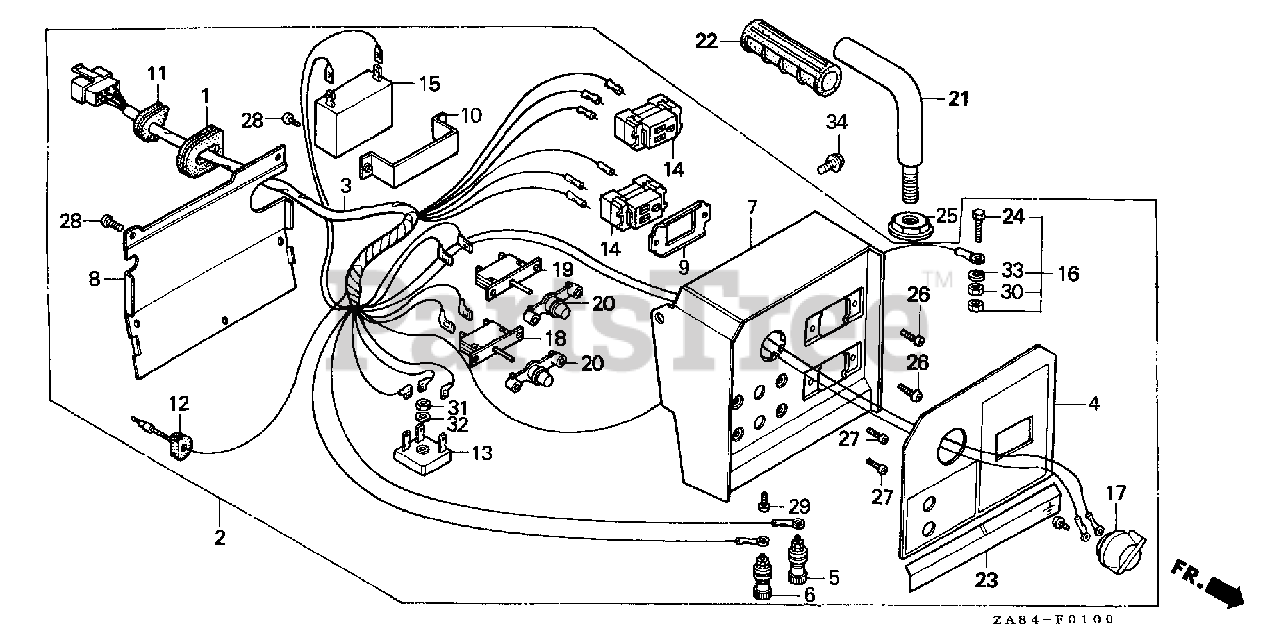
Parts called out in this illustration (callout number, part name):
1	GROMMET, WIRE
2	BOX ASSY., CONTROL *R8* (BRIGHT RED)
3	WIRE HARNESS ASSY.
4	MARK, SWITCH PANEL
5	TERMINAL, D.C. OUT (+)
6	TERMINAL, D.C. OUT (-)
7	BOX, CONTROL *R8* (BRIGHT RED)
8	COVER, CONTROL BOX
9	HOLDER, RECEPTACLE
10	HOLDER, CONDENSER
12	GROMMET, SWITCH WIRE
13	DIODE, D.C.
14	RECEPTACLE (15A/125V)
16	TERMINAL SET, GROUND
17	SWITCH ASSY., ENGINE STOP
17	SWITCH ASSY., ENGINE
18	PROTECTOR, CIRCUIT (DC)
19	PROTECTOR, CIRCUIT (A.C.)
20	LENS ASSY., PROTECTOR
21	HANDLE, CARRYING
22	GRIP, HANDLE
23	MARK, CONTROL BOX
24	BOLT, HEX. (6X22)
25	NUT, FLANGE (14MM)
26	SCREW, PAN (3X8)
27	SCREW, PAN (3X12)
28	SCREW, PAN (4X8)
29	SCREW, PAN (4X16)
30	NUT, HEX. (6MM)
31	NUT, HEX. (4MM)
32	WASHER, PLAIN (4MM)
33	WASHER, SPRING (6MM)
34	BOLT, FLANGE (6X10)
